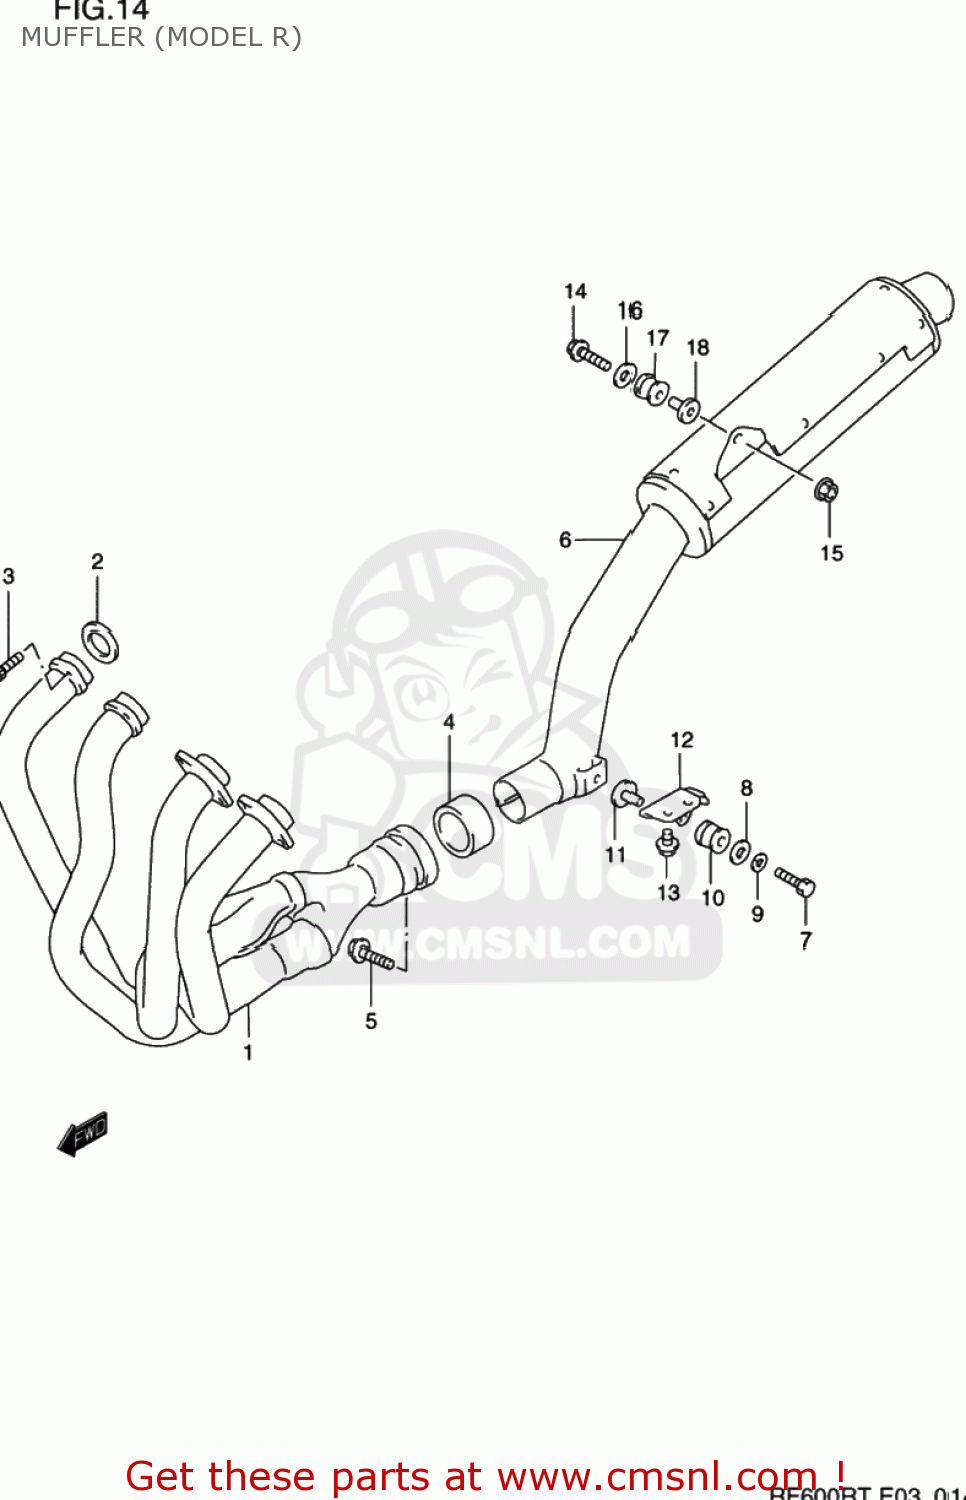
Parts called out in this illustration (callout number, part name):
1	PIPE COMP,EXHAUST
2	GASKET,EXHAUST PIPE
3	BOLT
4	CONNECTOR,MUFFLER
5	BOLT
6	BODY,MUFFLER
7	BOLT
8	WASHER (8.5X29X1.6)
9	LOCK WASHER
10	CUSHION
11	SPACER(8.6X12X24.2)
12	BRACKET,MUFFLER SUPPORT FR
13	BOLT
14	BOLT
15	NUT
16	WASHER (8.1X33X1.6)
17	CUSHION
18	SPACER(8.6X12X27.1)
